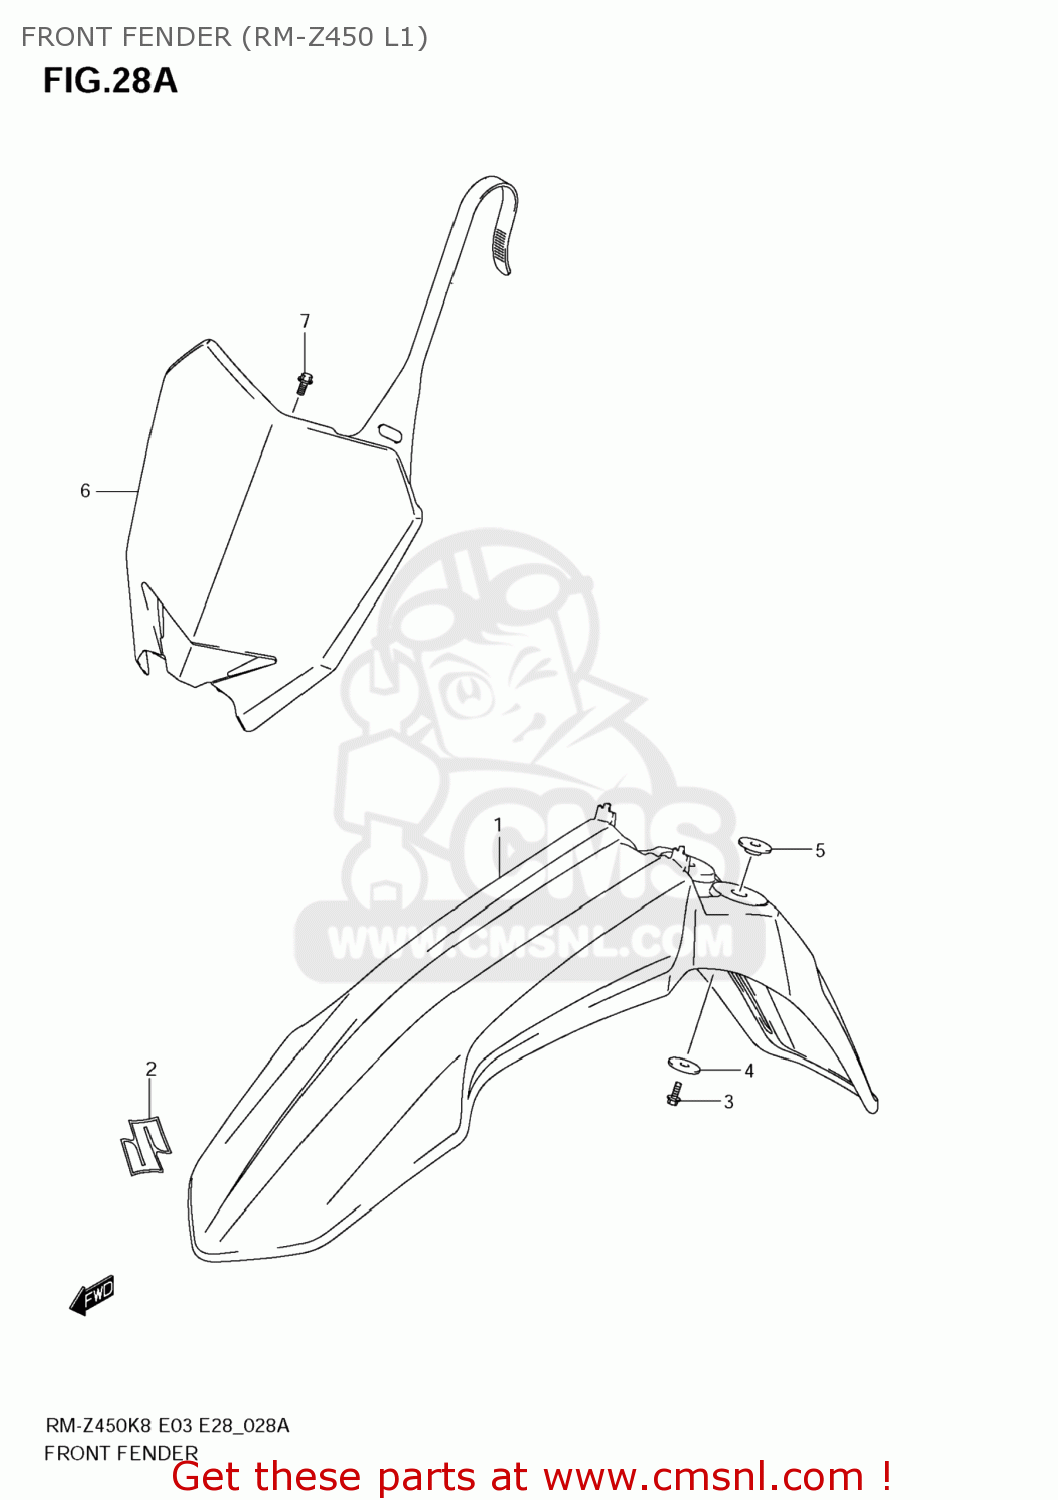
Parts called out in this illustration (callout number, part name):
1	FENDER,FR
2	EMBLEM,S
3	BOLT
4	WASHER,FUEL TANK FR
5	WASHER
6	PLATE.NUMBER FR
7	BOLT(6X12)
